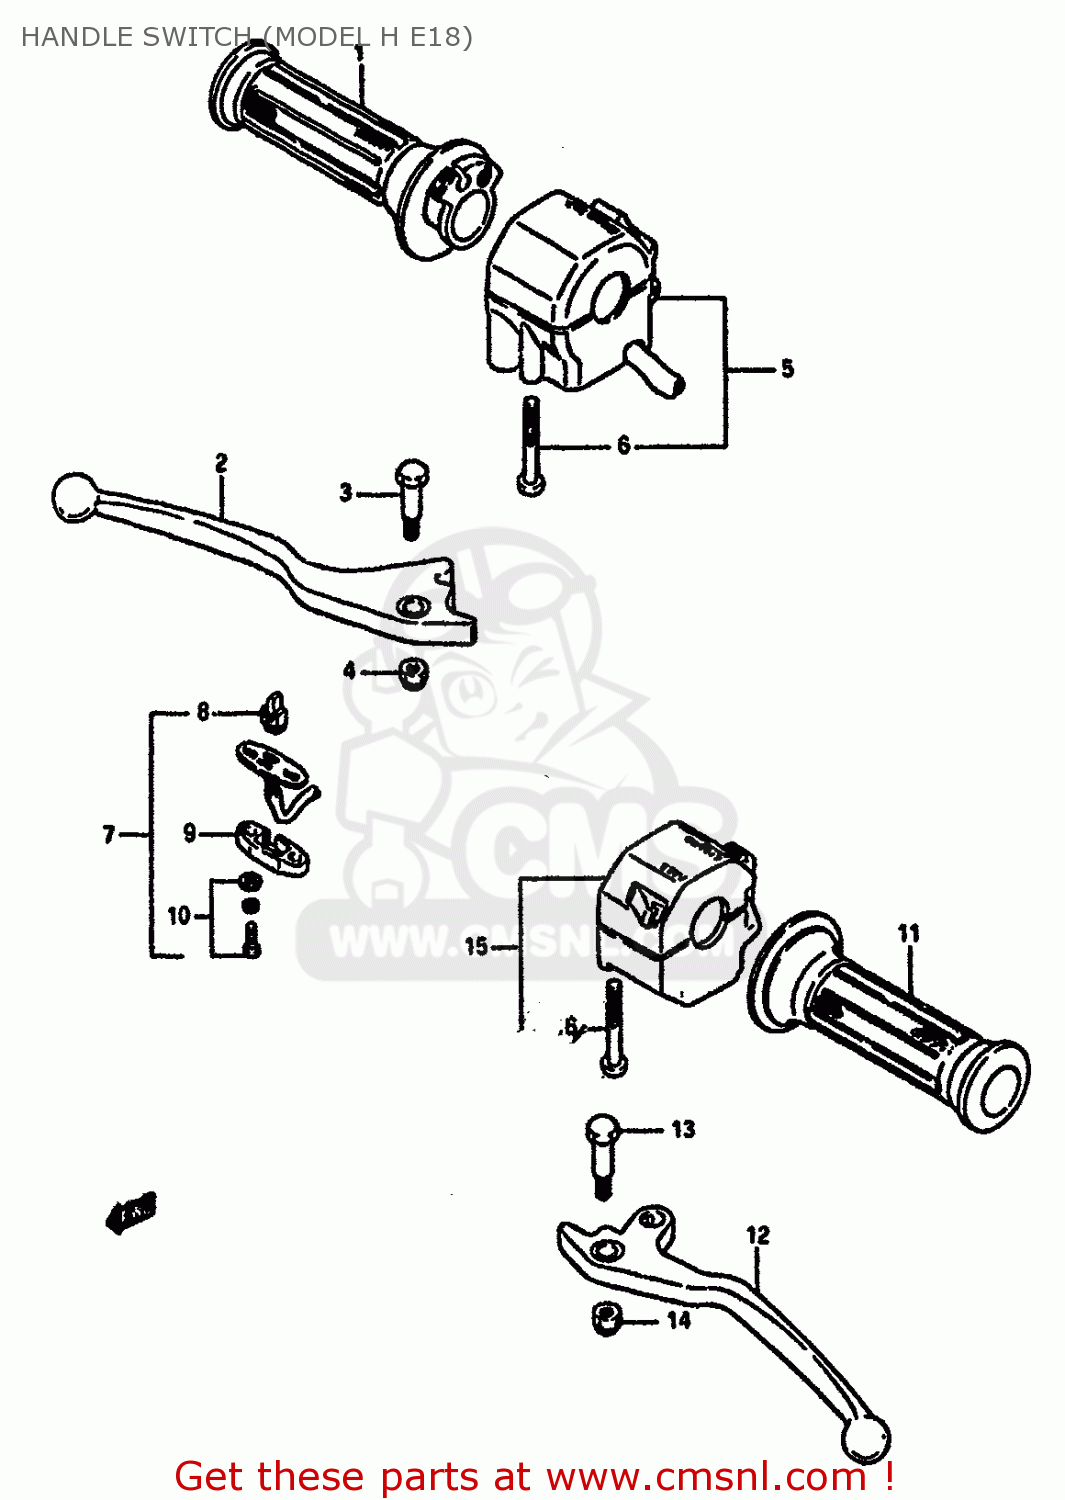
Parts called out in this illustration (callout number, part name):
1	GRIP,THROTTLE
2	LEVER,BRAKE
3	BOLT,LEVER
4	NUT
5	SWITCH ASSY,R
6	SCREW, 5X45
7	SWITCH ASSY,STOP
8	CONTACT,SWITCH
9	COVER,FR BK TERMINAL BASE
10	SCREW
11	GRIP,L
12	LEVER,CLUTCH (BLACK)
13	BOLT,LEVER
14	NUT
15	SWITCH ASSY, HANDLE LH
16	SCREW
